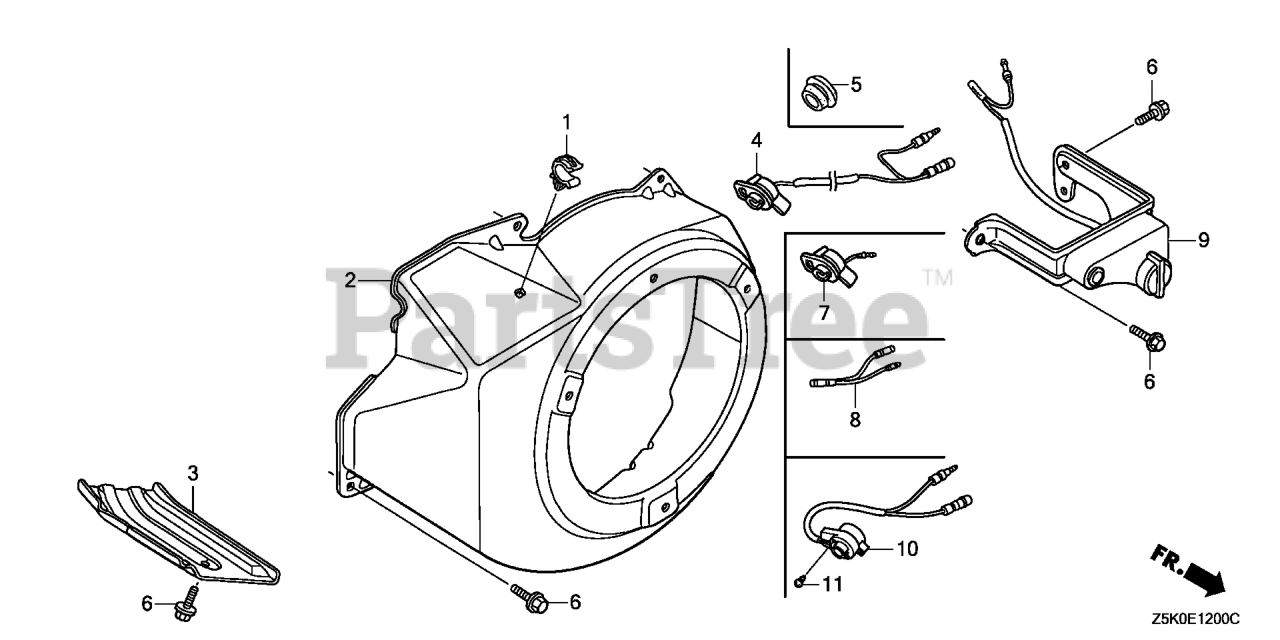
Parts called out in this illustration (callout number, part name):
1	CLIP, TUBE
2	COVER, FAN *NH1* (BLACK)
2	COVER, FAN *R280* (POWER RED)
5	GROMMET, DRAIN HOLE
6	BOLT, FLANGE (6X12) (CT200)
